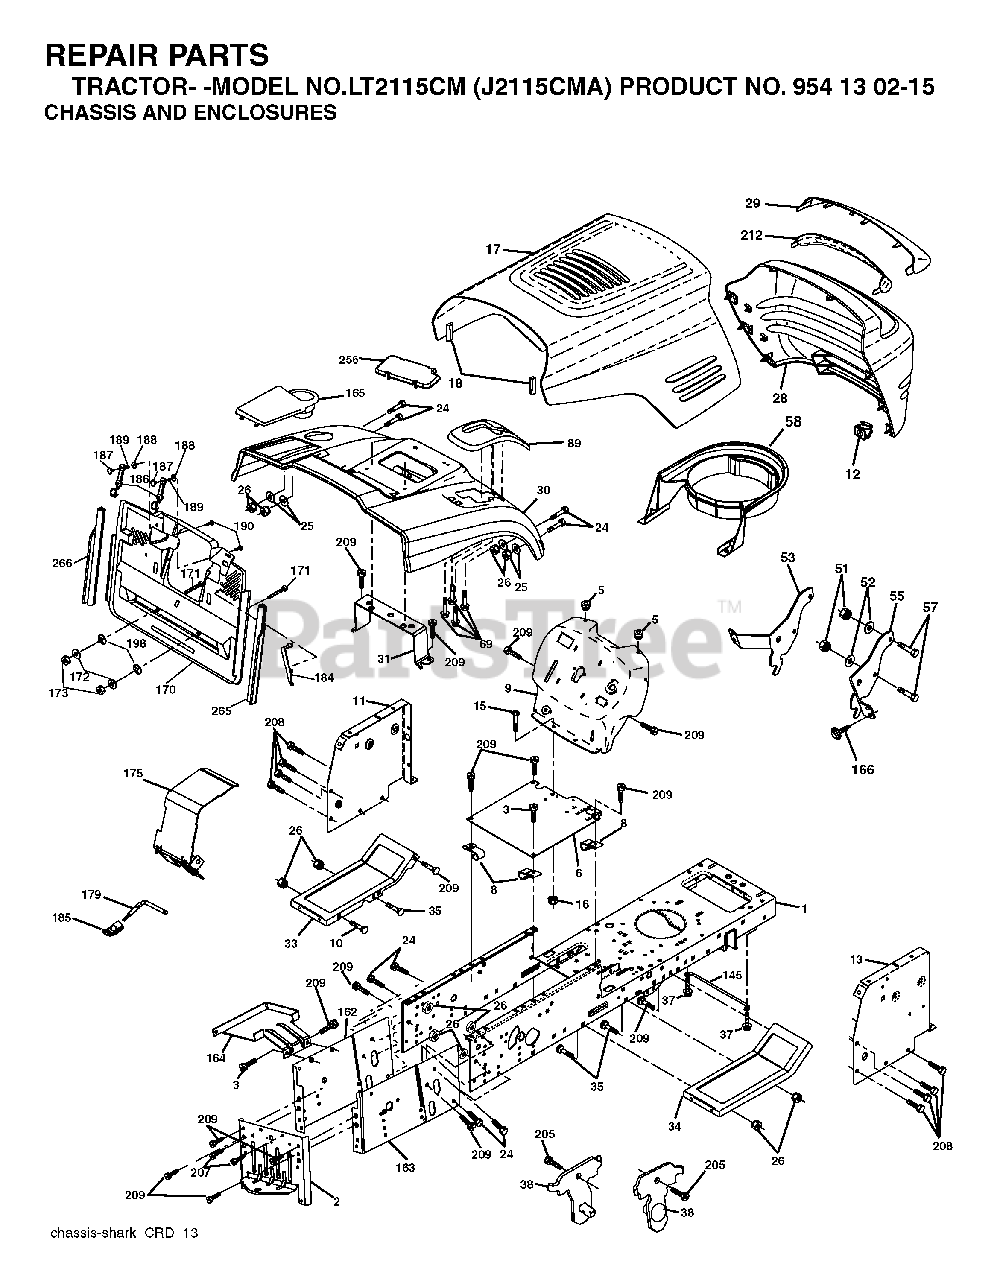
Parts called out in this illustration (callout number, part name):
1	CHASSIS
3	SCREW 3/8-16X3/4
5	BUMPER.RUBBER.HOOD
8	CLIP,INSULATOR
10	BOLT D
11	PANEL.DASH.LH.LTX
13	PANEL ASM, DASH RH
16	NUT
18	BUMPER.HOOD.LARGE.1.75"
25	WASHER
26	NUT
31	BRACKET SUPPORT FENDER
51	LOCKNUT
57	BOLT
69	SCREW.HI-LO.CONSOLE
145	ROD PIVOT CHASSIS/HOOD
164	SUPPORT
166	SCREW
171	BOLT
172	WASHER
186	LATCH ASSY
187	WELDNUT
189	LOCKWASHER
207	SCREW 5/16-18X1/2"
208	SCREW 3/8-16X1/2
209	SCREW, 3/8-16X3/4
